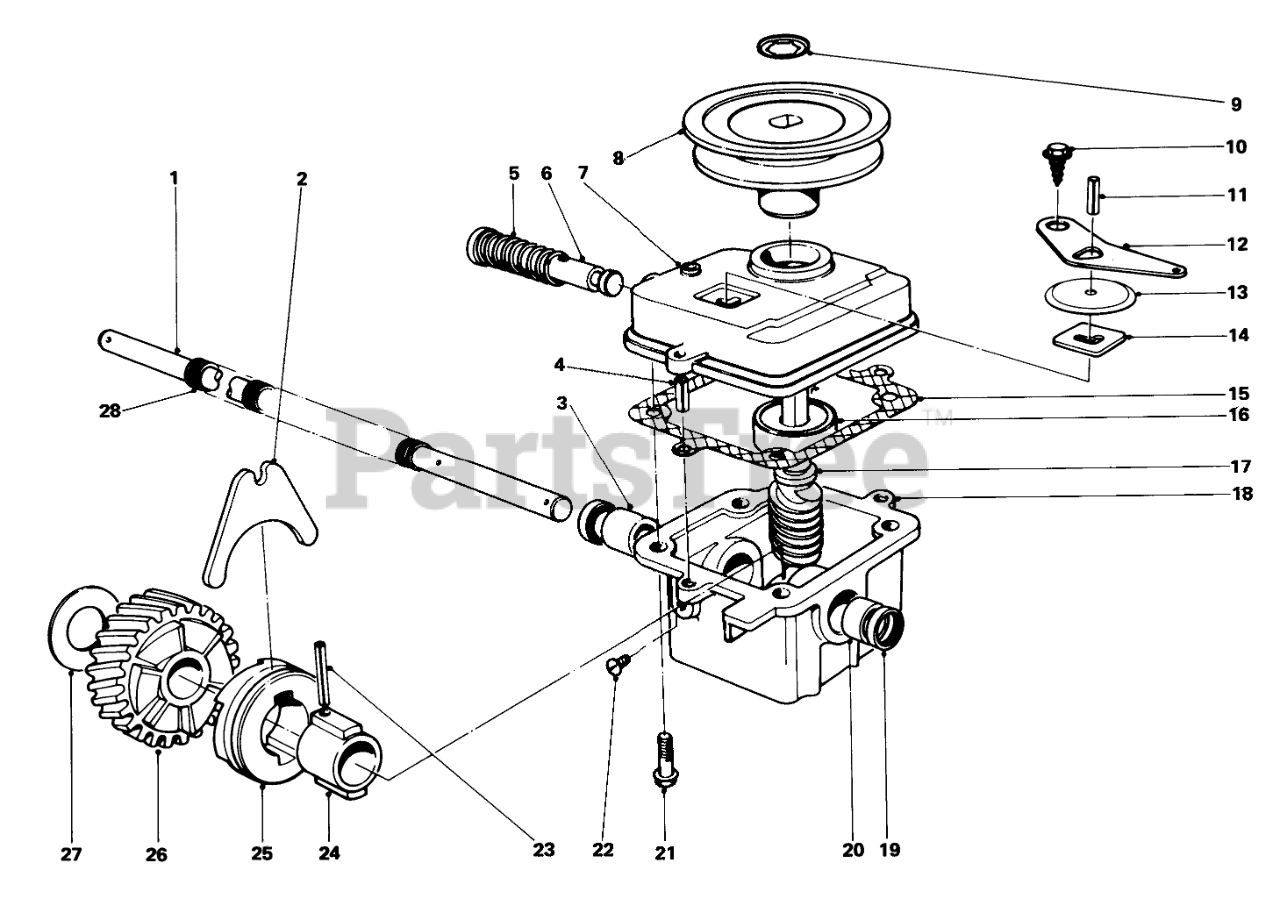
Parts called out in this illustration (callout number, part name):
1	DRIVE SHAFT (SERVCE)
2	SHIFTER FORK
3	Bushing
4	3/16 X 1/2 ROLL PIN
5	SPRING
6	Shift Rod
7	Case-Upper
8	PULLEY
9	PUSH-ON 93-3236
10	Screw
11	PIN-ROLL
12	SHIFTER ARM
13	TRANS DUST COVER
14	LATCH PLATE
15	GASKET
16	Bearing
17	Shaft Worm
18	Gear Case (Incl. Ref. #3, 19 &20)
19	Seal
20	Bushing
21	Screw
22	NYLON SCREW
23	COIL PIN
24	SLEEVE
25	CLUTCH JAW
26	Helical Gear
27	THRUST WASHER
28	COVER-SHAFT, DRIVE
